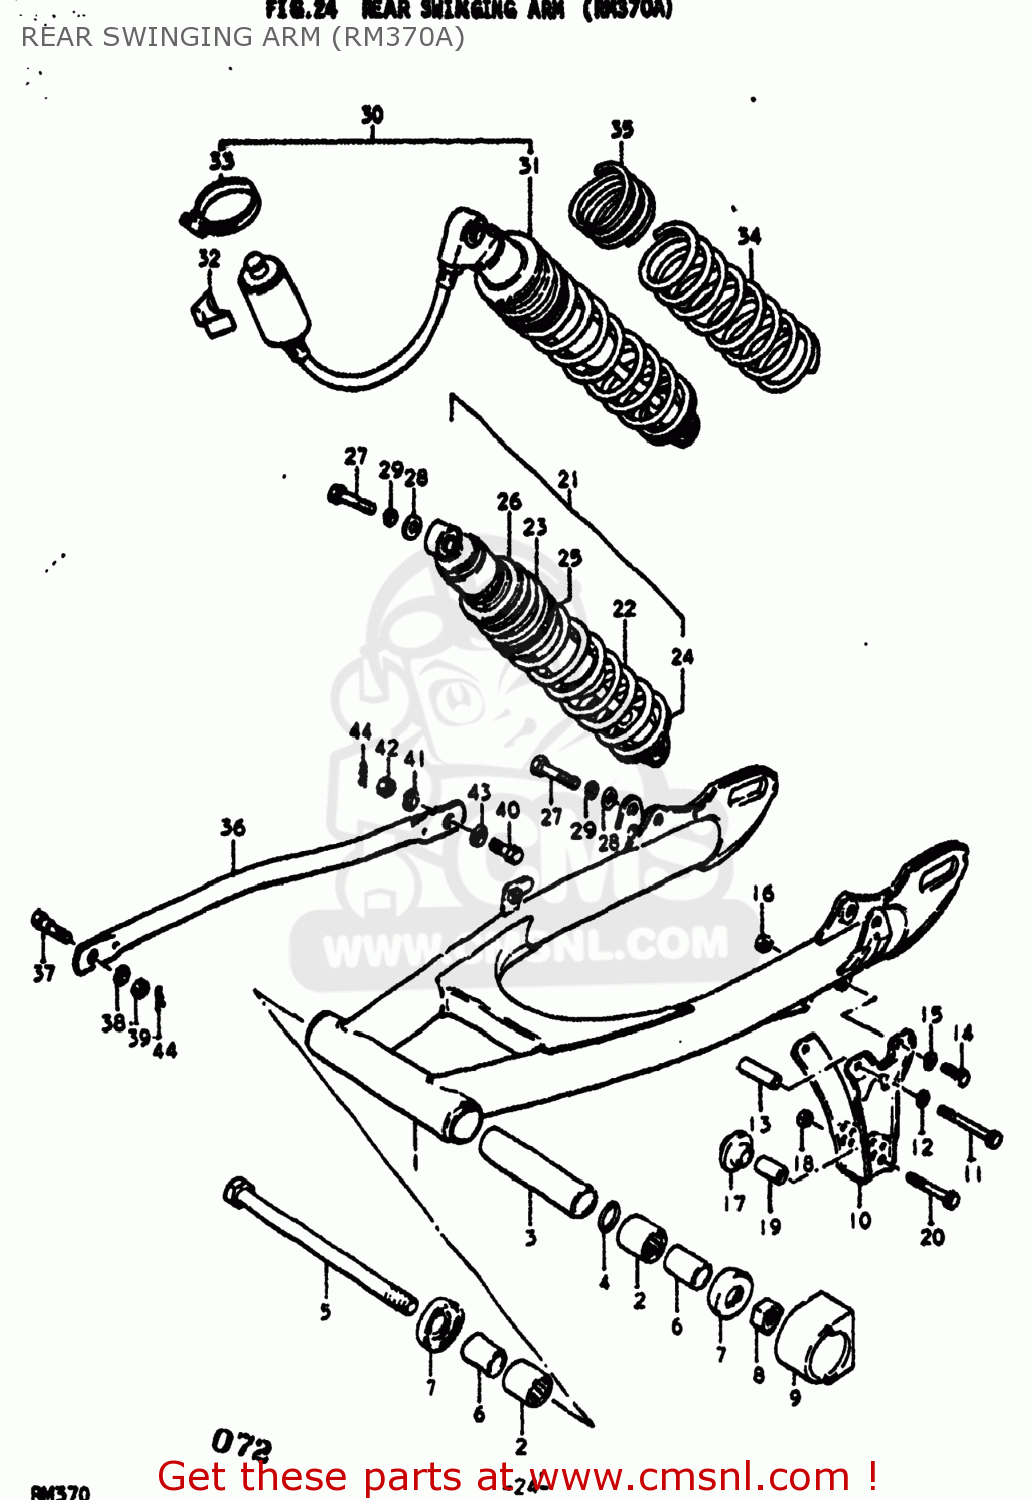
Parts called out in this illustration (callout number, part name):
1	SWING ARM ASSEMBLY,REAR
2	BEARING(20X28X25)
3	SPACER,REAR SWING ARM
4	O RING(D:1.9,ID:18.8)
5	SHAFT,REAR SWING ARM
6	SPACER(14X20X30)
7	THRUST BEARING IKO
8	NUT
9	BUFFER,CHAIN TOUCH DEFLECTOR
10	GUIDE,CHAIN
11	BOLT
12	LOCK WASHER
13	SPACER
14	BOLT
15	LOCK WASHER
16	NUT
17	RUBBER,CHAIN GUARD
18	NUT (6MM)
19	SPACER(6.5X10.5X22.5)
20	BOLT
21	ABSORBER ASSEMBLY,REAR SHOCK
22	SPRING
23	SPRING
25	SPRING
26	GUIDE,SPRING
27	BOLT 10X40
28	WASHER
29	LOCK WASHER
30	ABSORBER ASSEMBLY,REAR SHOCK
31	ABSORBER ASSEMBLY,REAR SHOCK
32	CUSHION,RR SHOCK ABSORBER
33	CLAMP
34	SPRING
35	SPRING
36	TORQUE LINK,REAR
37	BOLT(8X22.5)
38	LOCK WASHER
39	NUT
40	BOLT(10X31)
41	LOCK WASHER
42	NUT
43	WASHER
44	CLIP
